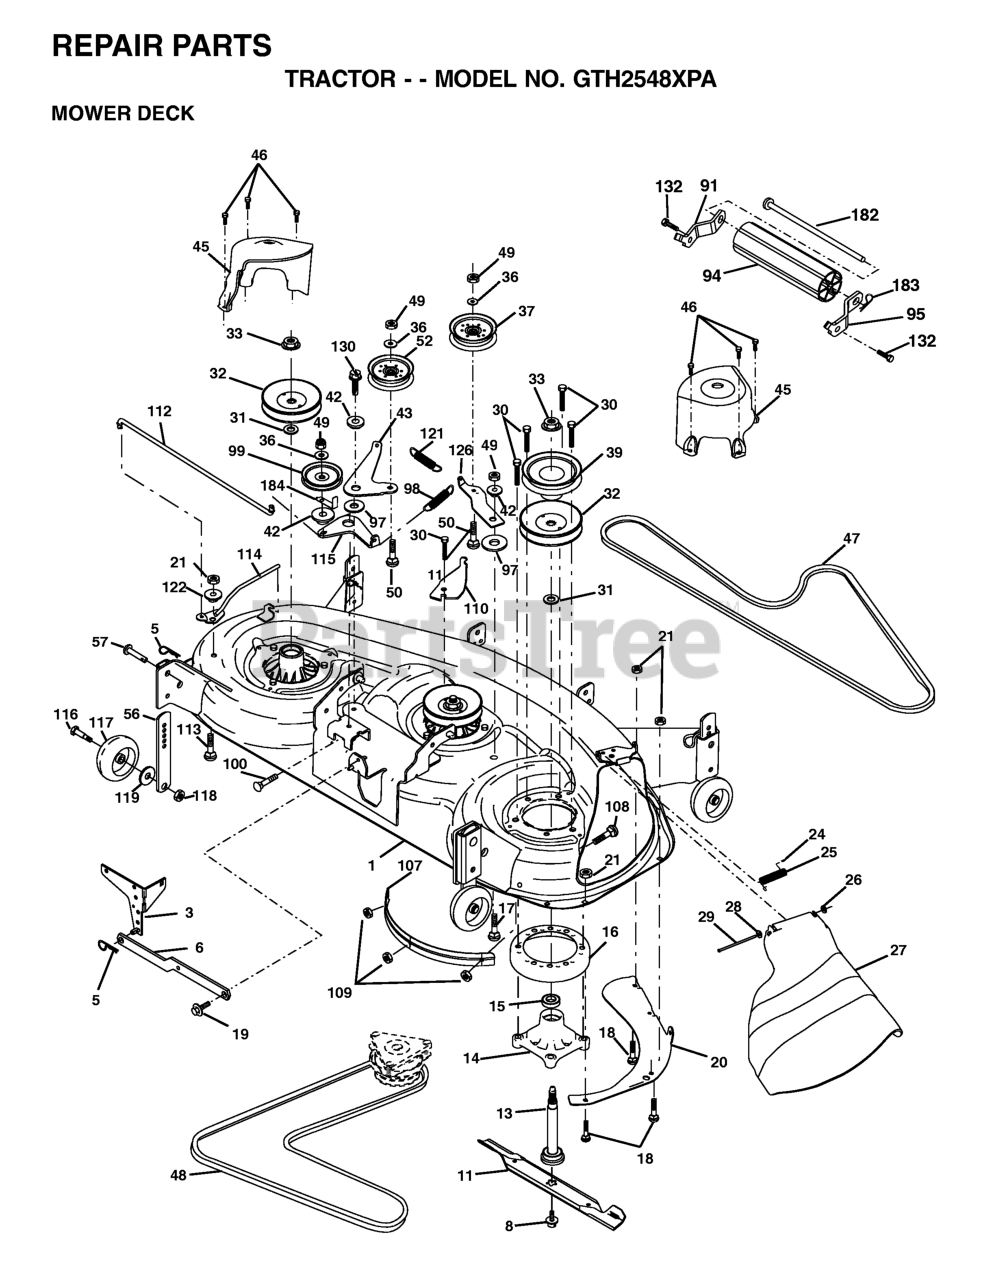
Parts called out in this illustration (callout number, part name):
1	DECK WELDMENT
3	BRACKET ASM.
5	RETAINER-SPRNG RB
6	BAR SWAY DECK
8	BOLT 7/16 ASM BLADE
11	48" HI-LIFT BLADE
13	SHAFT ASM W/LOWER BEARING
14	HOUSING, MANDREL 48"
16	STRIPPER.MANDREL.ROUND.BLACK
17	BOLT
18	BOLT
19	BOLT SHD 5/16-18
20	BAFFLE, VORTEX MWR
21	LOCKNUT
24	CAP-SLEEVE LT
25	SPRING, TORSION
26	NUT PUSH M
27	DEFLECTOR SUBS TO 532 180655
28	Washer 11/32 x 5/8 x 16 Ga SD
29	ROD.HINGE
30	SCREW, WASHER HEAD
31	WASHER
32	PULLEY, MANDREL
33	NUT, FLG TOPLOCK 9/16"
36	WASHER
37	PULLEY.IDLER.FLAT
39	PULLEY.DRIVEN.DECK.48'
42	SPACER RETAINER
43	ARM, IDLER SECONDARY
45	COVER, MANDREL DECK
46	SCREW.1/4-20X5/8
47	V-BELT, MWR SECONDARY
48	V-BELT PRIMARY 48"
50	BOLT.3/8-16X1.50
52	PULLEY.IDLER.FLAT.46.PR.DR.
56	BAR.ADJUST.WHEEL.ANTI.SCALP.BL
57	RIVET.PIN.HEAD.YELLOW.
90	BOLT RB
91	BRKT.NOSEROLLER.LH.48"
93	Washer 1 17/32 X 7/8 X 16 Ga
94	NOSE ROLLER 48"
95	BRKT.NOSEROLLER.RH.48"
97	HARDENED WASHER
98	SPRING PRIMARY DRIVE
99	PULLEY,IDLER"V"
107	BAFFLE.VAC.EDGE.MOWER.48"
109	NUT.CROWNLOCK.1/4
110	ARM, SPRING SECONDARY
112	LEVER, TENSION RELIEF LINK
114	LEVER ASM, TENSION RELIEF
115	ARM, SPRING TENSION RELIEF
116	BOLT, SHOULDER
117	WHEEL GAGE DONUT
118	LOCKNUT
119	WASHER.5/16.FLAT.STE.STD.
121	SPRING.DRIVE.SECONDARY.48".DEC
122	BUSHING, PIVOT TENSION RELIEF
126	ARM, IDLER PRIMARY DECK
130	SCREW 3/8-16X1
132	SCREW 3/8-16X3/4
182	ROD.ROLLER.NOSE.NARROW.48"
183	SPRING RETAINER
184	KEEPER BELT IDLER PLATED
